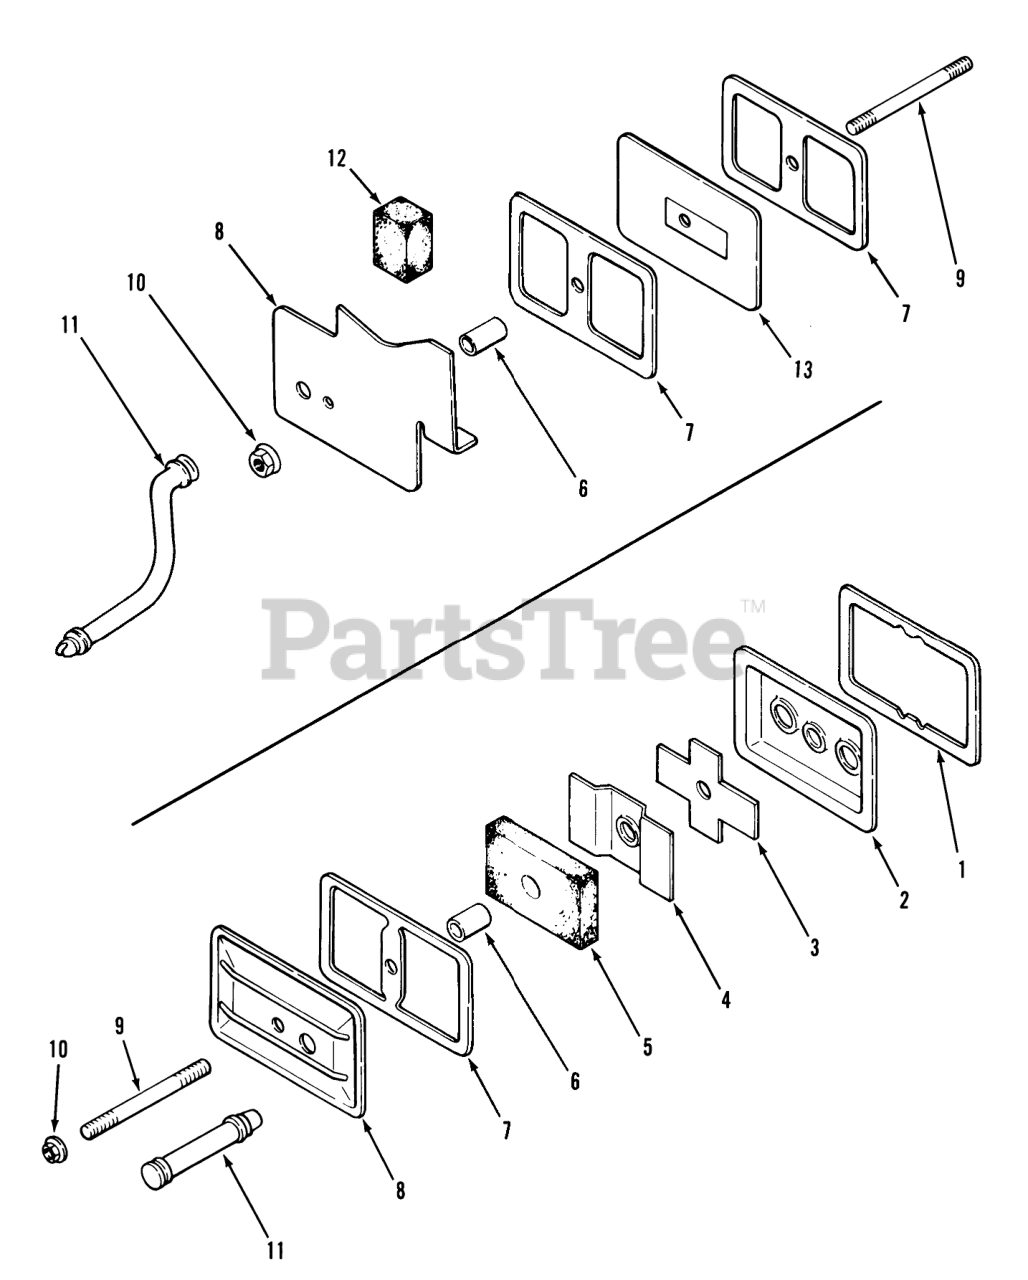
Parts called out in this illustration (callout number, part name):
1	Gasket
2	Plate
4	Baffle
5	Filter
6	Breather Seal 308 Only
7	Valve Cover Gasket 308 Only
8	Valve Cover 308 Only
9	Valve Cover Stud 308 Only
10	Palnut
11	Breather Hose 308 Only
12	Filter 308 Only
13	Breather 308 Only
